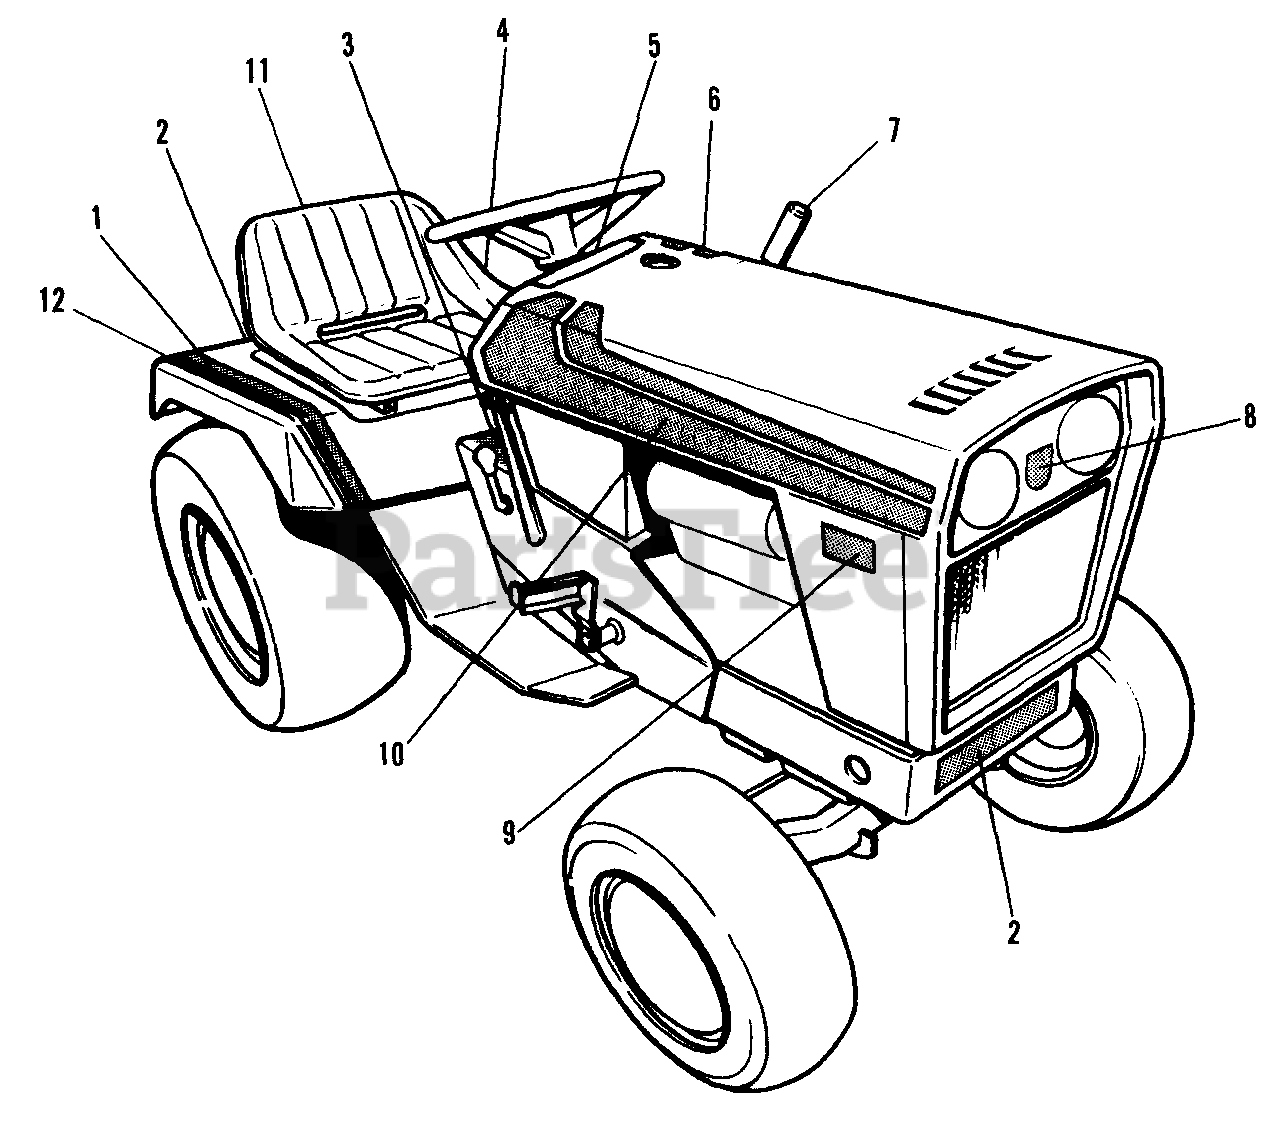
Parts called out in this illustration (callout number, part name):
1	DECAL, Seat Deck, R.H.
2	DECAL, Simplicity
3	DECAL, Console, Shuttle
4	DECAL, Seat Deck, L.H.
5	DECAL, Dash, Shuttle
6	DECAL, Hood, Baron, L.H. (7114)
6	DECAL, Hood, Sovereign, L.H. (7116)
7	FILM, Lift Lever
8	DECAL, Simplicity, Grille
9	DECAL, Model 7114, Semi-Automatic
9	DECAL, Model 7116, Semi-Automatic
10	DECAL, Hood, Baron, R.H. (7114)
10	DECAL, Hood, Sovereign, R.H.
10	BATTERY (on battery)
10	DECAL, Caution (on top of engine)
10	DECAL, Drive Belts (inside hood)
10	DECAL, Warning (under seat deck)
10	DECAL, Adjustment (on LH side plate)
